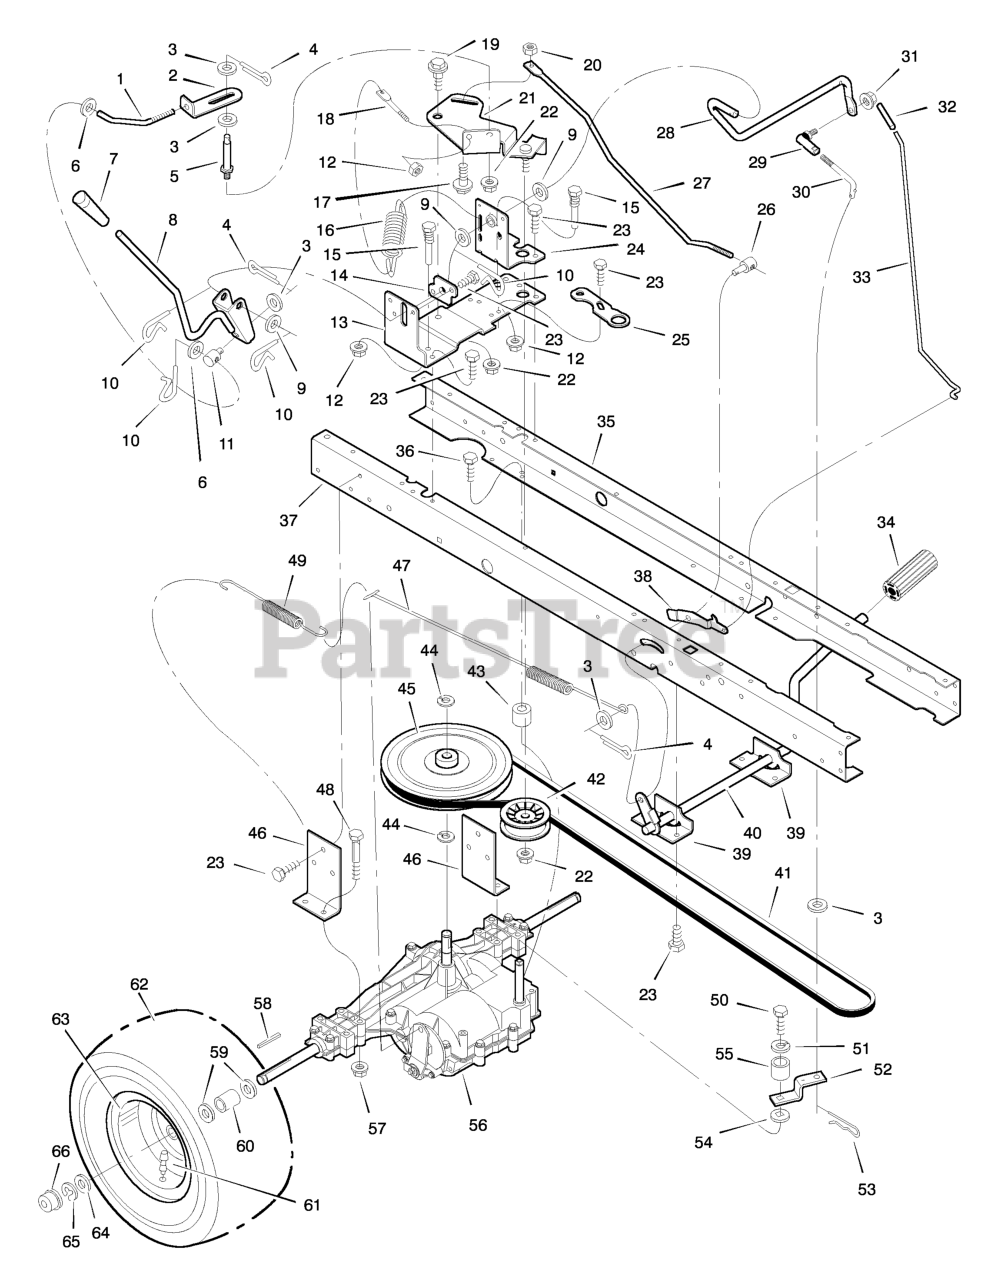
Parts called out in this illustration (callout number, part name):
1	Rod, Adjuster
2	Link, Clutch
3	Washer
4	Pin, Cotter
5	Spacer, Stud
6	Washer
8	Lever, Shift
9	Washer
10	Pin, Hair
12	Nut, Flange
13	Bracket, Shifter
14	Plate, Pivot
15	Guide, Belt
16	Spring, Extension
17	Bolt, Shoulder
18	Stud, Spring
19	Bolt, Shoulder
20	Locknut
21	Arm Assembly, Idler
22	Locknut
24	Bracket, Shift
25	Plate, Shift
26	Nut, Adjuster
27	Rod, Clutch
28	Rod, Shift
29	Joint, Ball
30	Link, Shift
31	Locknut
33	Rod, Parking Brake
34	Pedal
35	Frame, Left
37	Frame, Right
38	Latch, Parking Brake
39	Bracket, Pedal
40	Lever, Clutch/Brake
42	Pulley, Idler
44	Ring, Snap
45	Pulley, Drive
46	Bracket, Left Transaxle
47	Spring, Extension
48	Bolt
49	Spring, Extension
51	Lockwasher
52	Yoke, Shift
53	Pin, Hair
55	Spacer
56	Transaxle **
57	Nut, Flange
58	Key, Square
61	Stem, Valve
62	Tire *
63	Wheel & Tire Assembly
65	E- Ring
66	Cap, Hub
67	Bracket, Right Transaxle
